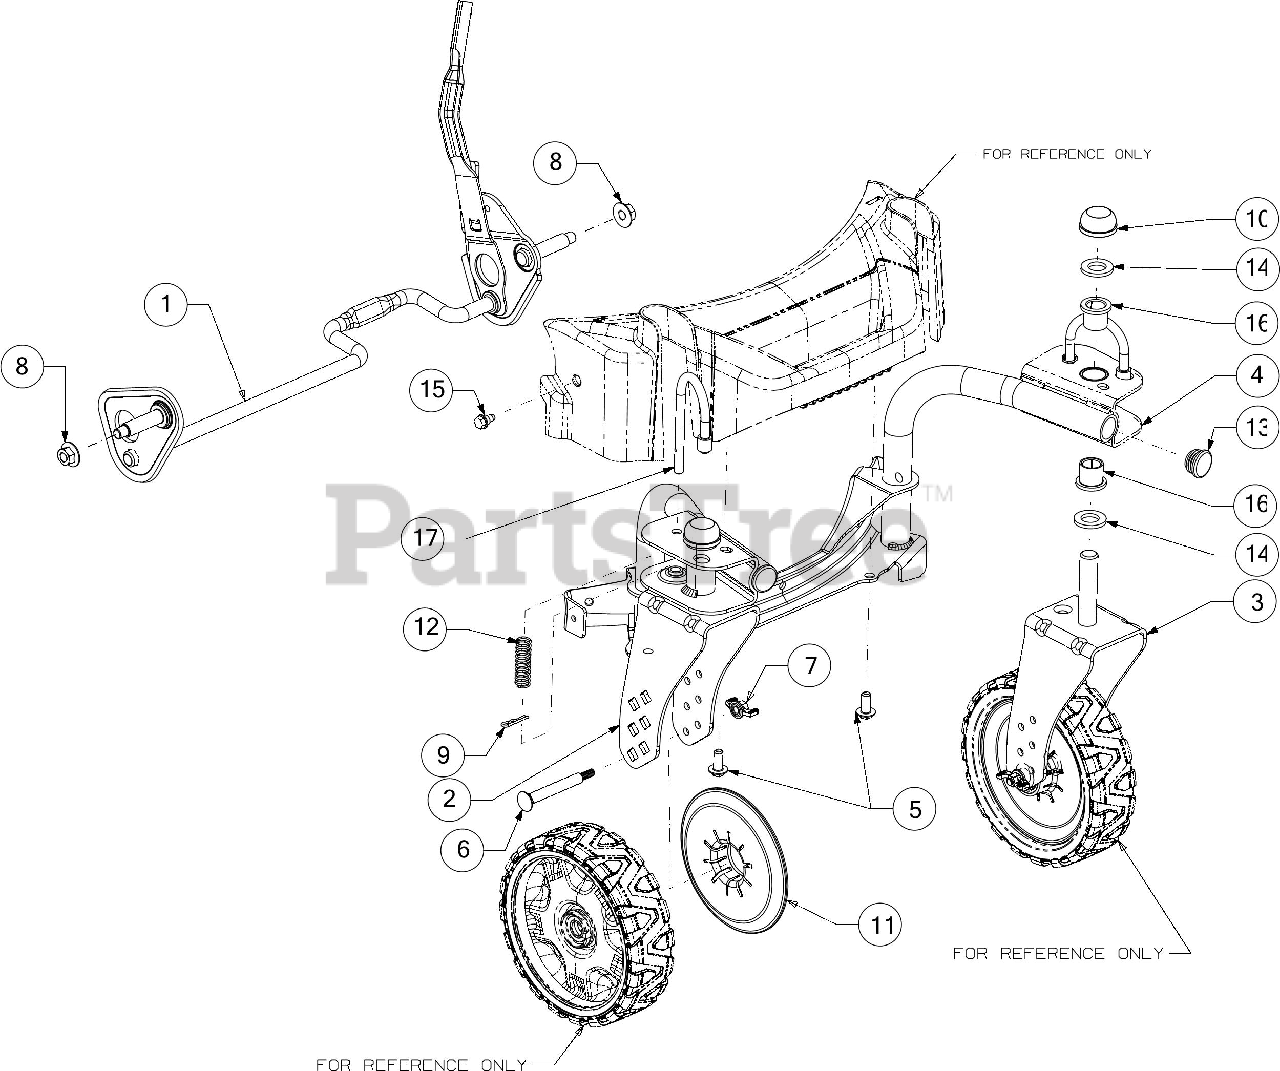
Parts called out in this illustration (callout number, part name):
1	HEIGHT AXLE ASSEMBLY
2	CASTER BRACKET ASSEMBLY (RH)
3	WHEEL BRACKET ASSEMBLY (LH)
4	CASTER BRACKET ASSEMBLY
5	SCREW 5/16-14 X .750
6	CASTER AXLE
8	FLANGE LOCK NUT
9	COTTER PIN .072 DIA
11	DUST COVER 7"
12	COMPRESSION SPRING
14	FLAT WASHER
15	SHOULDER SCREW 1/4-20 X .50
16	BEARING:FLANGE .631 ID
